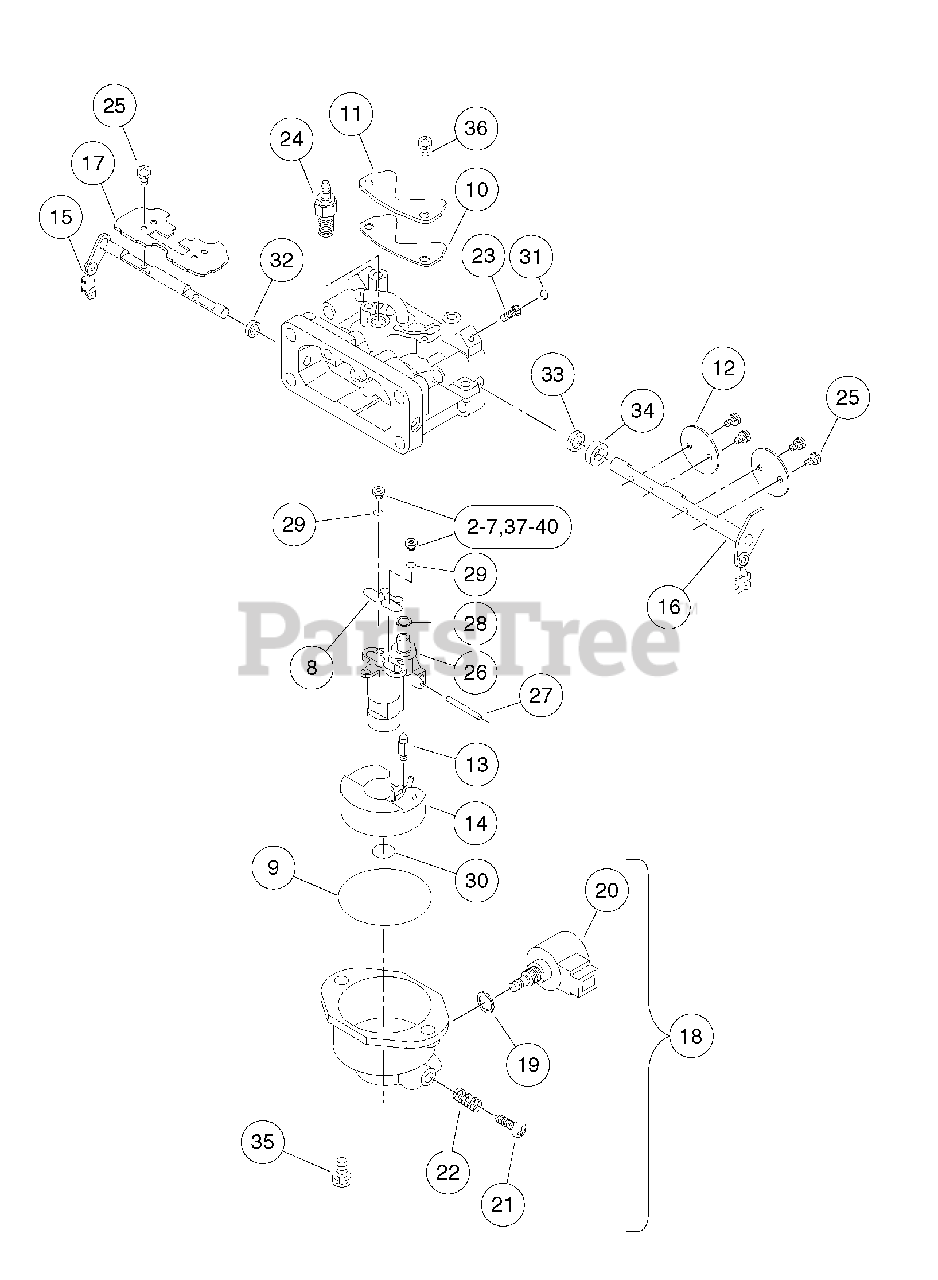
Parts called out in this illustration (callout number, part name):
1	Asm, Carburetor, FH680D
2	Kit, Jet, 6600 Ft +, Fh680d
3	Jet, Push In #96, FH680D (6600 ft and higher (2000 m and higher))
4	Instructions, Kit, Jet, Push In
5	Kit, Jet, 3300-6600 Ft, Fh680d
6	Jet, Push In #99, FH680D (3300-6600 ft (1000-2000 m))
7	Instructions, Kit, Jet, Push In
8	Gasket, Fh680d
9	Gasket, Carburetor, Dia. 52
10	Gasket, Cover, Fh680d
11	Cover, Slow Passage, Fh680d
12	Valve, Throttle, Fh680d
13	Valve, Float, Fh680d
14	Float, Carburetor, Fh680d
15	Shaft, Carburetor, Fh680d
16	Shaft, Carburetor, Throttle
17	Valve, Carburetor, Fh680d
18	Asm, Chamber, Float, Fh680d
19	Gasket, Carburetor, Fh680d
20	Solenoid, Carburetor, Fh680d
21	Screw, Drain, Carburetor
22	Spring, Carburetor, Fh680d
23	Needle, Jet, Fh680d
24	Heater, Carburetor, Fh680d
25	Screw, Carburetor, M3 X 6
26	Spacer, Carburetor, Fh680d
27	Pin, Carburetor, Fh680d
28	O-ring, Carburetor, Dia. 6.5
29	O-ring, Carburetor, Fh680d
30	O-ring, Carburetor, Dia. 9
31	Plug, Expansion, Carburetor
32	Seal, Carburetor, Dia. 5.9
33	Seal, Carburetor, Fh680d
34	Collar, Carburetor, Fh680d
35	Screw, Carburetor, M5
36	Screw, Carburetor, M4
37	Kit, Jet, 0-3300 ft. FH680D
38	Jet, Push In #102, FH680D (0-3300 ft (0-1000 m))
39	Instructions, Kit, Jet, Push In
40	Jet, Push In, #104 FH680D (0-3000 ft (0-1000m))
